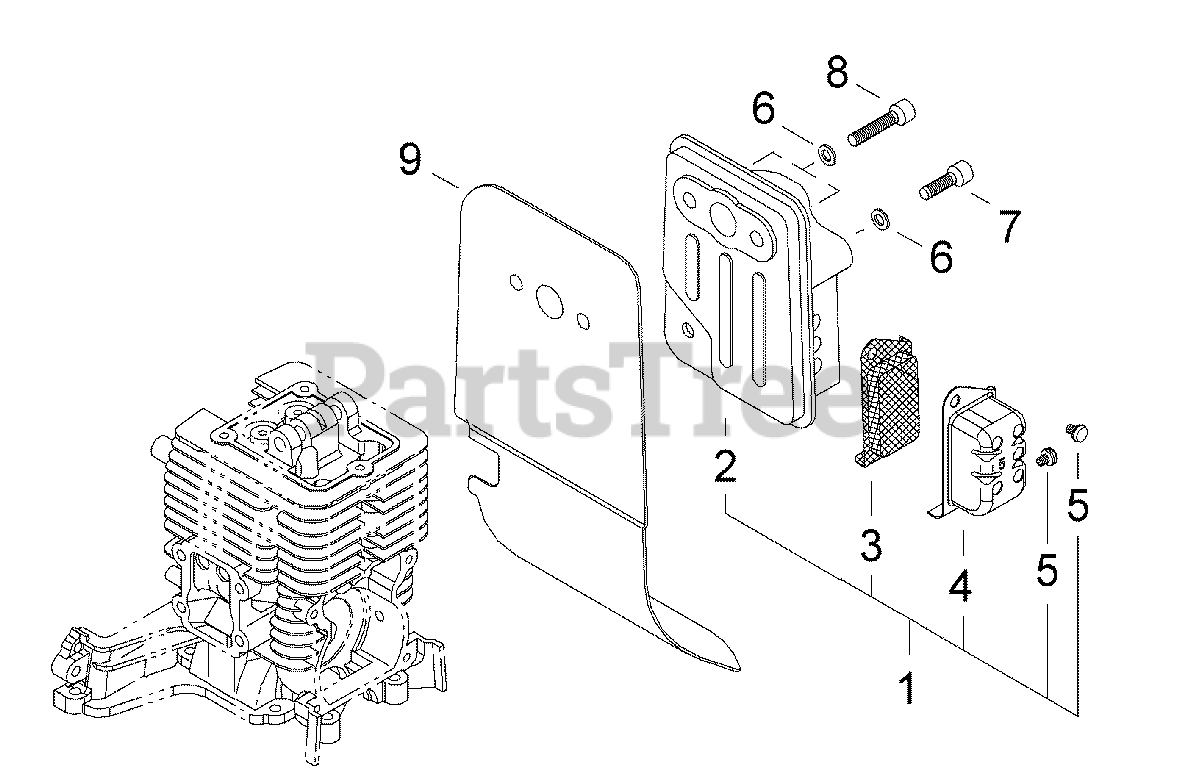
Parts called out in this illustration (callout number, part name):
1	MUFFLER ASSY
2	MUFFLER
3	SCREEN, SPARK ARRESTOR
4	GUIDE, EXHAUST
5	SCREW - 4X6
6	WASHER - 5
7	SCREW - 5X16
8	SCREW - 5X25
9	SHIELD, EXHAUST
